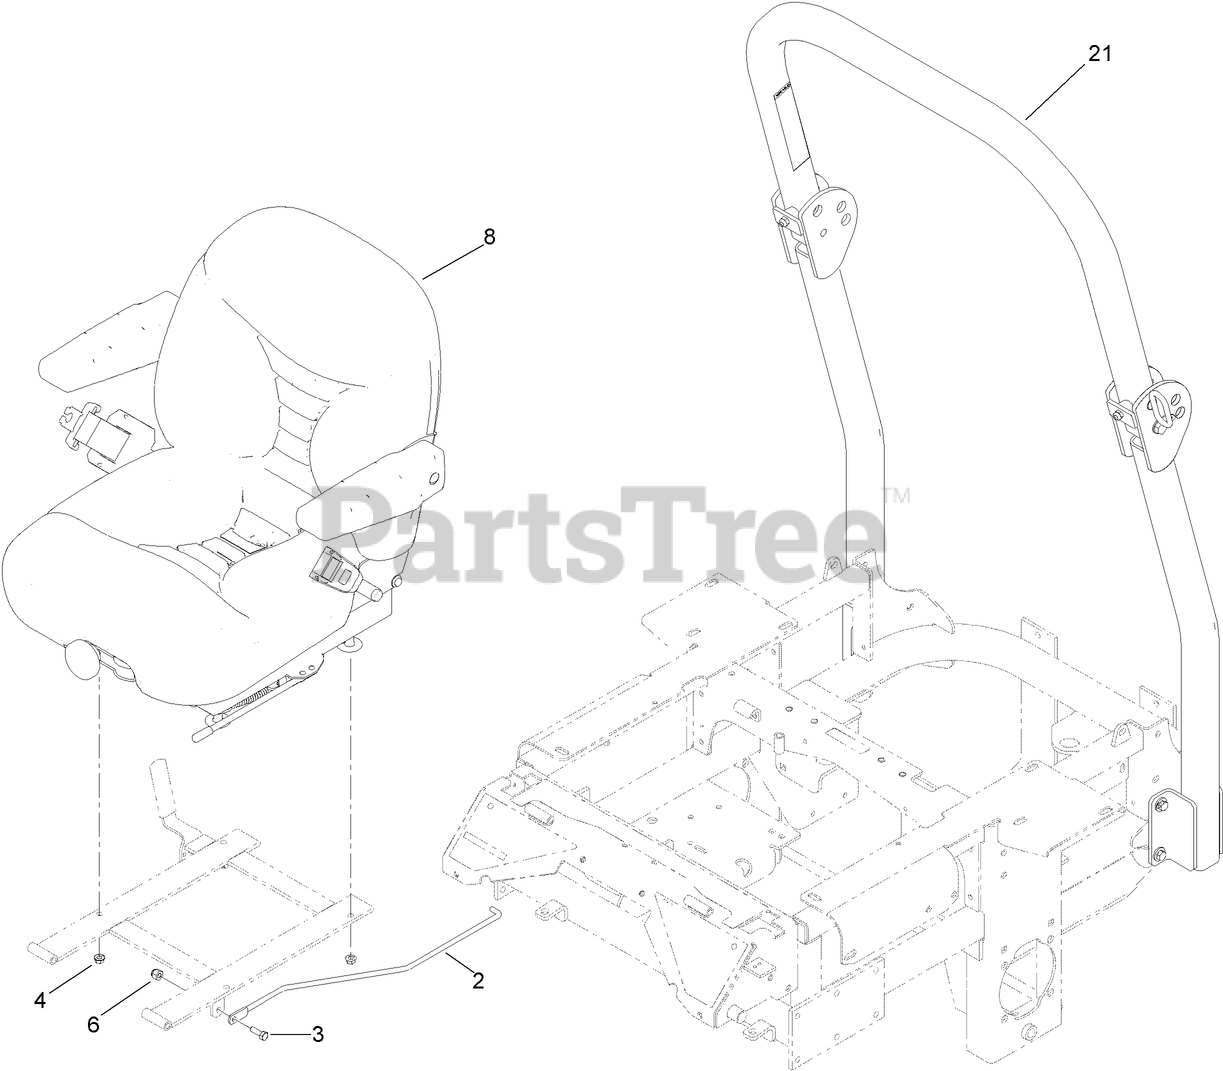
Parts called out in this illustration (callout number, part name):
2	ROD-PROP, SEAT
3	SCREW-HH
4	NUT-HF
6	NUT-LOCK, NI
8	DELUXE SEAT ASM
21	ROPS KIT
